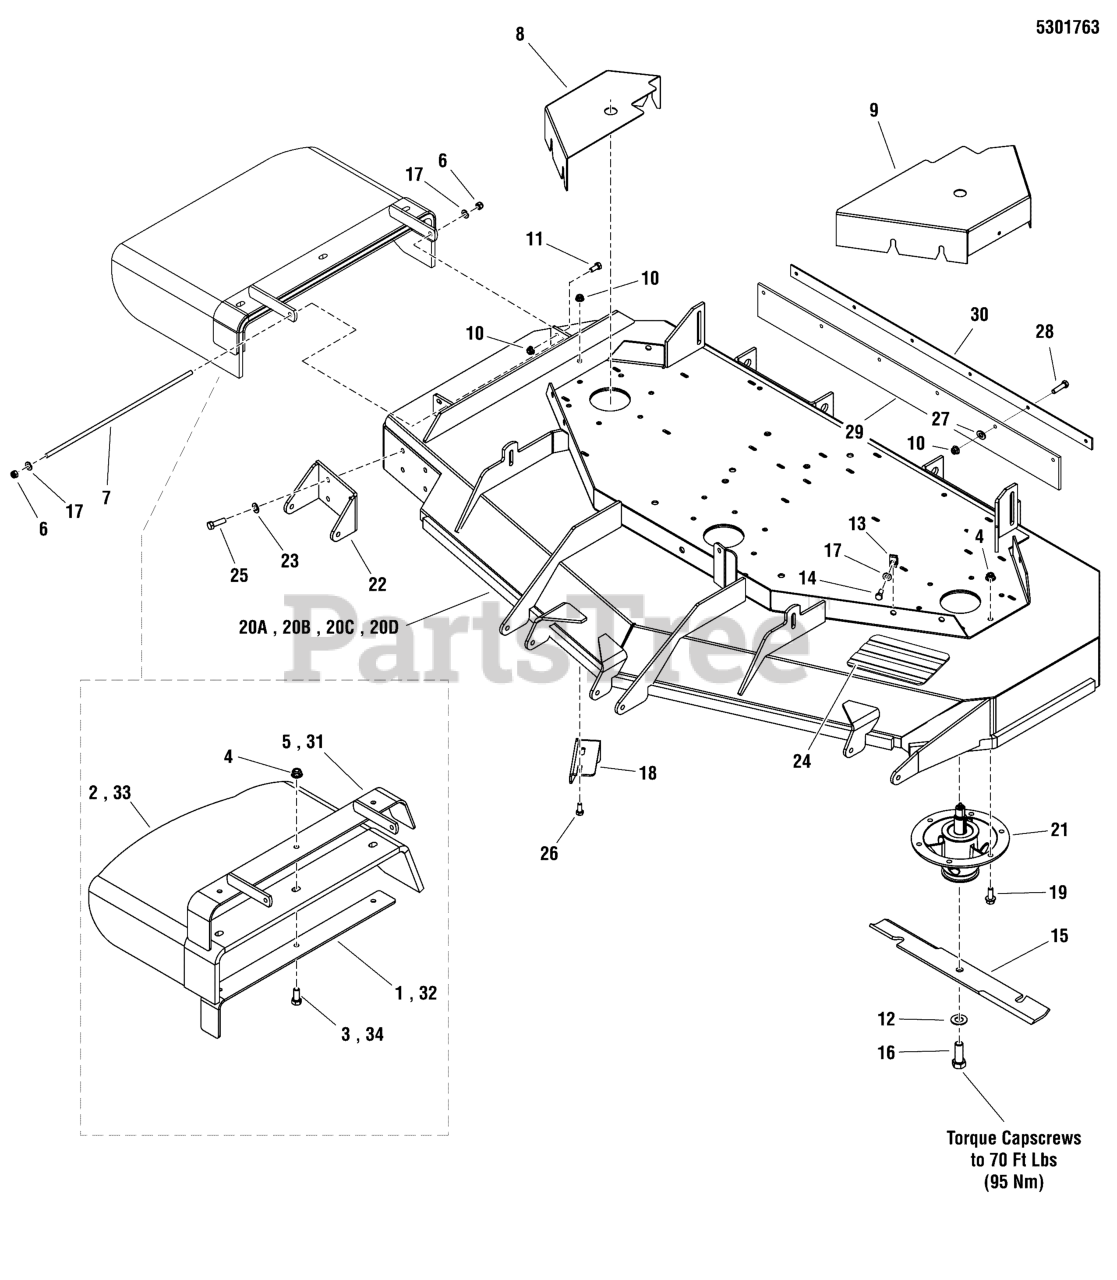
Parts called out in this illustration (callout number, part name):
1	SUPPORT, DISCHARGE CHUTE, 61/72 - BLK
2	CHUTE, DISCHARGE, BEND RUBBER (SV)
3	BOLT, 3/8-16 X 1-1/2" GD5 CZ
4	NUT, 3/8-16 HEX NYLOCK FLANGE
5	WELD, FRAME CHUTE, 61 - BLK
6	NUT, 5/16-24 HEX NYLON LOCK
7	ROD MOUNT, CHUTE 61"
8	GUARD, RH - 61 - S200XI - RED
9	GUARD, 61 - LH - RED
10	NUT, 5/16-18 HEX NYLOCK FLANGE
11	BOLT, 5/16-18 X 3/4 GD5
12	WASHER, 5/8 GRADE 8, YZ
13	BODY CLIP, 5/16-18-7GA MATERIAL
14	BOLT, 5/16-18 X 3/4 GD5
15	BLADE, 21" (SET OF 3)
16	BOLT, 5/8-11 X 1-3/4 GD8
17	WASHER, 5/16" SAE
18	PLATE, DEFLECTOR - BLK
19	BOLT, 3/8-16 X 1, FLANGE, GD 5, CZ
20A	DECK SHELL W/DECALS,61-200XT-SPR/MASS
20B	DECK SHELL W/ DECALS, 200XT 61 - SPR RED
20C	DECK SHELL W/ DECALS, 61" - S200XT
20D	DECK SHELL W/ DECALS, 61" - S200XT
21	SPINDLE ASSM, CAST IRON 8.0-6 BOLT
22	PLATE, BRACKET, ANTI SCALP - RED
23	WASHER, 3/8 SAE
24	SAFETY WALK, 9.75 X 6.00
25	BOLT, 3/8-16 X 1-1/4" GD5 CZ
26	BOLT, 5/16-18 X 3/4, CARRIAGE
27	5/16 PUSH-ON NUT RETAINER, STL, CZ
28	BOLT, 5/16-18 X 1 GD5 YZ
29	FLAP, STRIPER, 61 DECK, IS3100 S200X
30	PLATE, SUPPORT - BLK
31	WELD, MOUNT DISCHARGE, CHUTE - BLK
32	SUPPORT, DISCHARGE CHUTE - BLK
33	CHUTE, RUBBER DISCHARGE (5104442)
34	BOLT, 3/8-16 X 1-1/2, CARRIAGE, GD5, CZ
